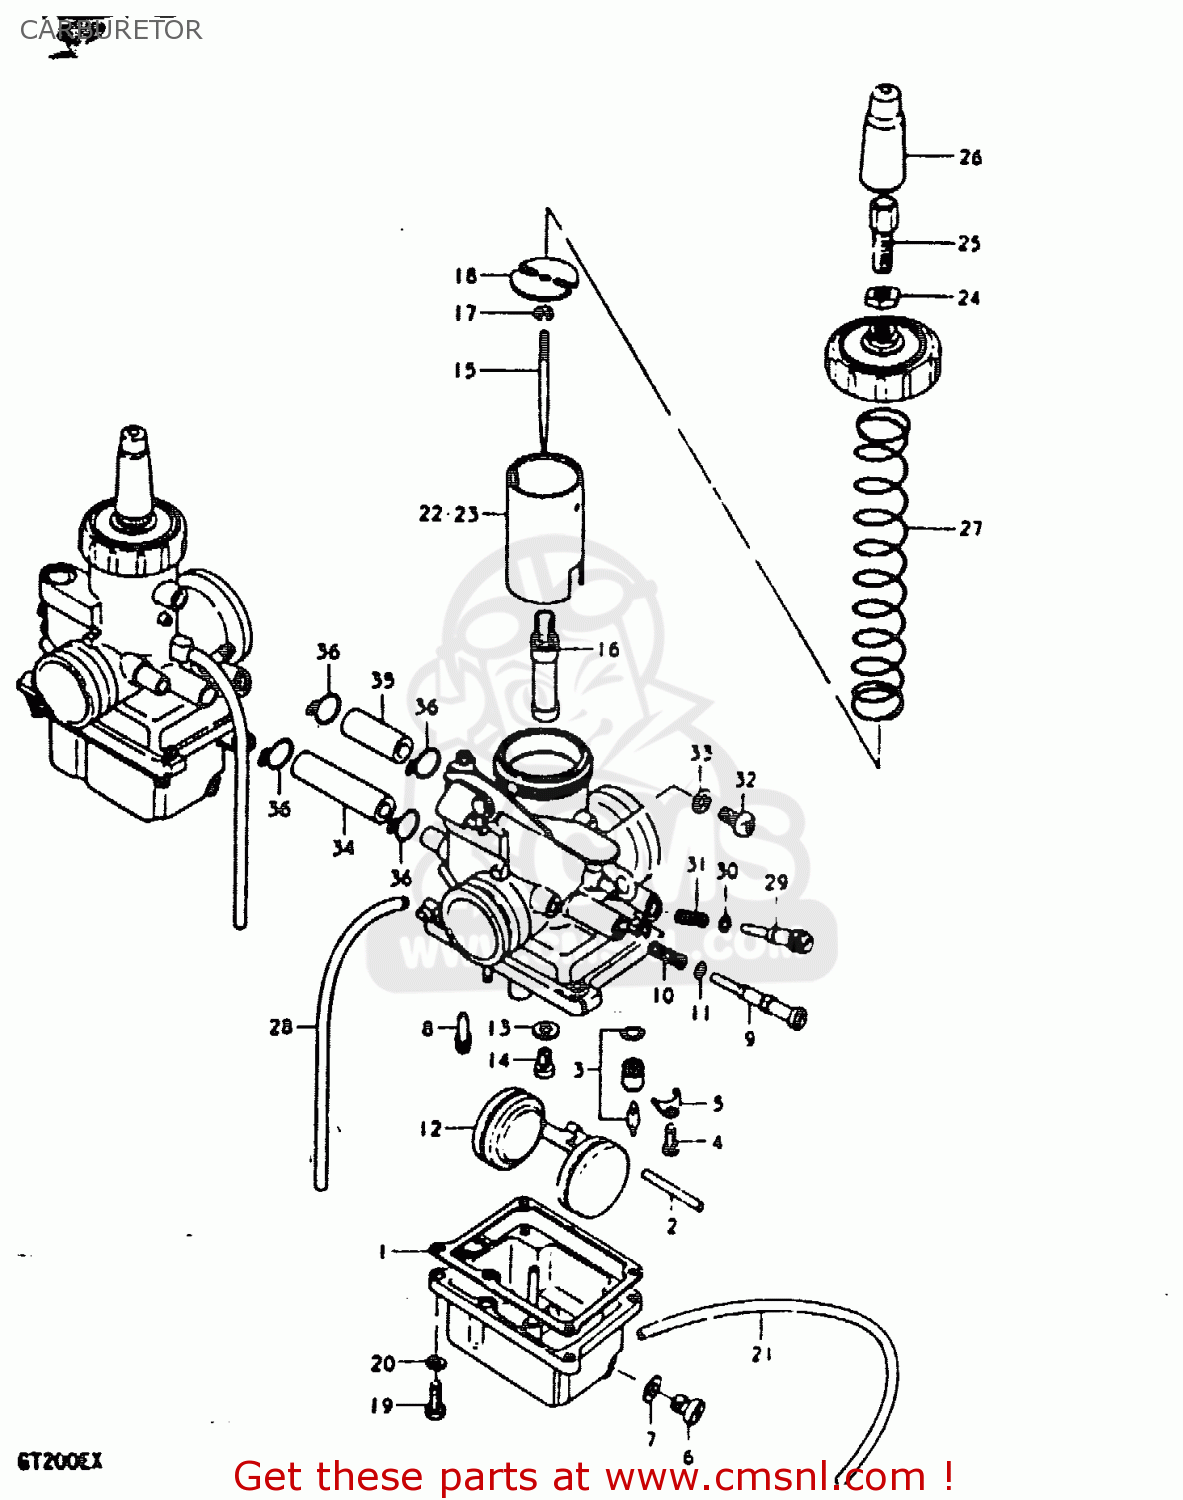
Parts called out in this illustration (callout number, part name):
1	GASKET,FLOAT CAHMBER (NAS)
2	PIN,FLOAT
3	VALVE ASSY,NEEDLE
4	SCREW
5	PLATE,NEEDLE VALVE FITING
6	PLUG
7	GASKET,DRAIN,PLUG (NAS)
8	JET
9	SCREW, STOP
10	SPRING
11	O RING
12	FLOAT
13	WASHER
14	JET
15	NEEDLE, JET (4CG1-3)
16	JET, NEEDLE (O-8)
17	CLIP
18	PLATE, SPRING
19	SCREW
20	LOCK WASHER
21	HOSE
22	VALVE, THROTTLE LH
23	VALVE, THROTTLE RH
24	NUT
25	ADJUSTER,CABLE
26	BOOT
27	SPRING,THROTTLE VALVE
28	HOSE
29	SCREW,PILOT AIR
30	O RING
31	SPRING
32	SCREW
33	GASKET,DRAIN PLUG (NAS)
34	HOSE, STARTER (L:40)
35	HOSE
36	CLIP,CARBURETOR HOSE
